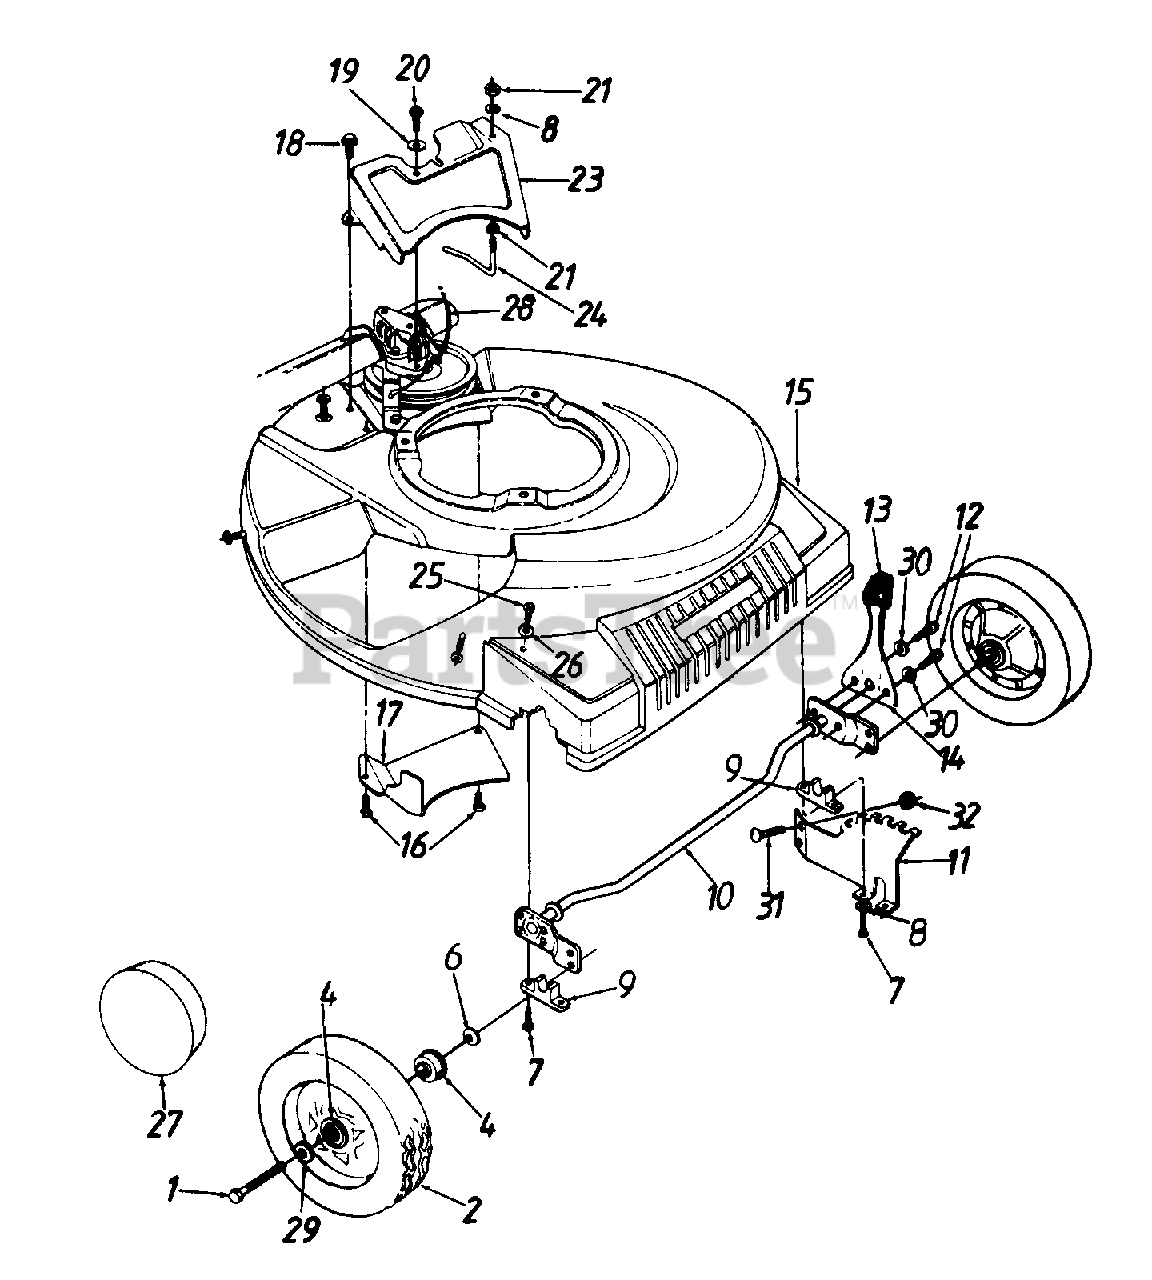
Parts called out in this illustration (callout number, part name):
1	Front Axle Bolt
2	Wheel Ass'y. Comp. (Beige)
4	Flange Ball Brg. .501" I.D.
6	Bell-Wash. .380" I.D. x .88
7	Hex Wash. Hd. Scr. 1/4-20 x 1" Lg.
8	L-Wash. 1/4" I.D.
9	Block Bushing
10	Axle Ass'y.
11	Height Adj. Bracket
12	Hex Wash. Hd. TT-Tap Scr. 1/4-20 x .38" Lg.
13	Knob
14	Spring Lever
15	Plastic Front End (Black)
16	Hex B-Tap Scr. 1/4" x .38"
19	Bell-Wash. .265" I.D. x .75"
20	Hex Wash. Hd. B-Tap Scr. 1/4 x .62" (Spec.)
21	Hex Nut 1/4-20 Thd.
25	Torx Truss Hd. Scr. 5/16 x .75"
26	Bell-Wash. .345" I.D. x .88" O.D.
27	Hub Cap (Beige)
28	S.P. Cable 50" Lg.
29	Wave Wash. .51" I.D. x .75" O.D.
30	External L-Wash. 1/4" I.D.
31	Carr. Bolt 1/4-20 x .5" Lg.
32	Hex L-Nut 1/4-20 Thd.
